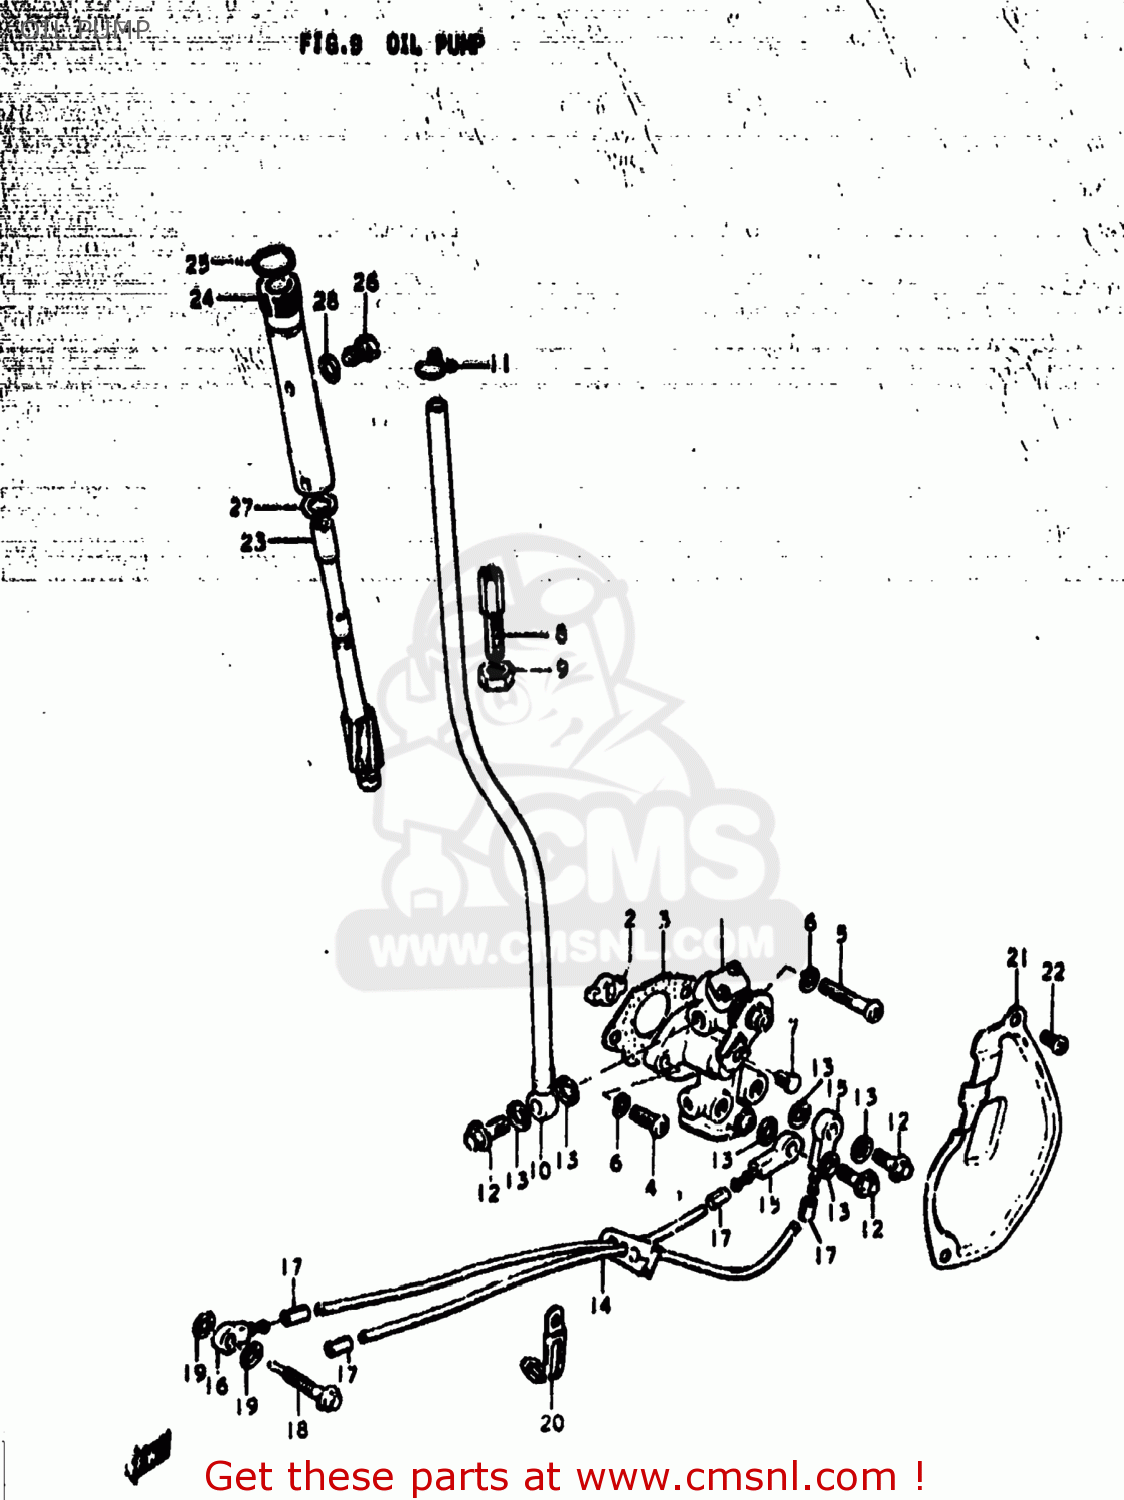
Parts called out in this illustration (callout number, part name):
1	PUMP ASSEMBLY,OIL
2	PIECE,OIL PUMP DRIVE
3	GASKET,OIL PUMP (MCA)
4	SCREW
5	SCREW
6	LOCK WASHER
7	TERMINAL,CABLE
8	BOLT
9	NUT
10	HOSE,OIL NO.1
11	CLIP
12	UNION BOLT
13	GASKET(6.2X11X1).2 (NAS)
14	HOSE,OIL NO.2
15	VALVE,CHECK
16	UNION
17	CLIP
18	UNION
19	GASKET(6.2X11X1).2 (NAS)
20	CLAMP L:35
21	CAP,OIL PUMP INSPECTION
22	SCREW
23	GEAR,TACHOMETER DRIVEN
24	SLEEVE,TACHOMETER DRIVE
25	O RING(D:1.3,ID:9.6)
26	BOLT(6X12)
27	WASHER(8X13.7X1)
28	WASHER
